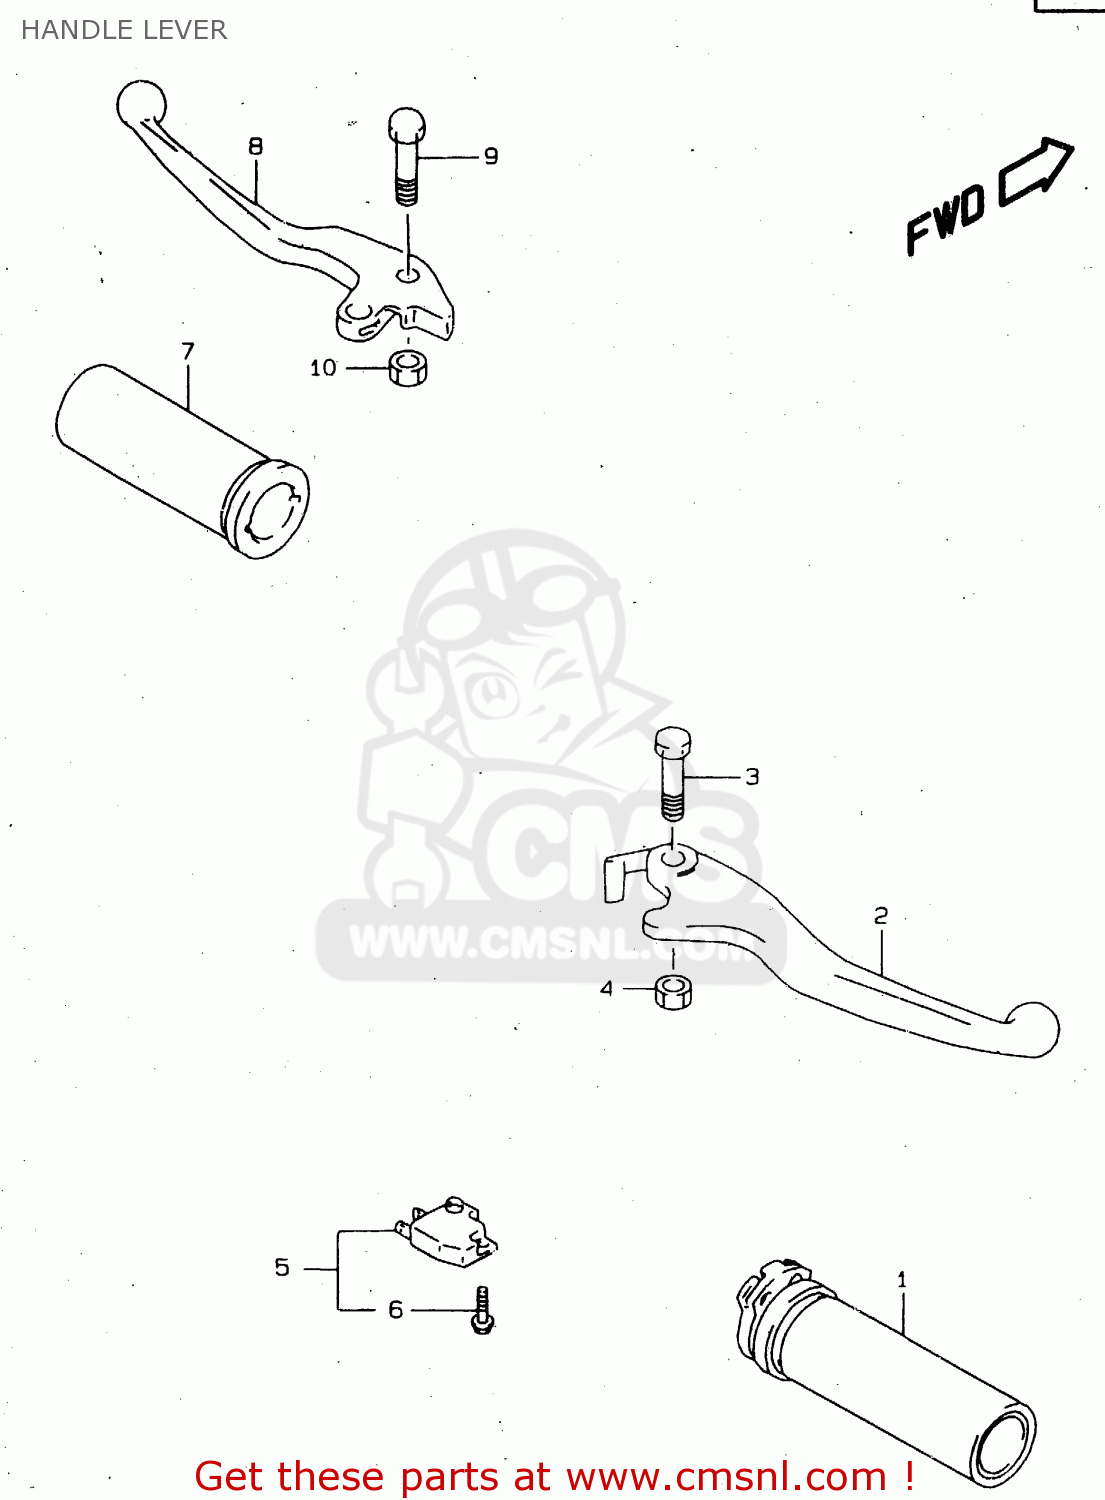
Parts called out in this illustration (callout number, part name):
1	GRIP,THROTTLE
2	LEVER,BRAKE
3	BOLT,LEVER SET
4	NUT 6MM
5	SWITCH ASSEMBLY,STOP
6	SCREW
7	GRIP,L
8	LEVER,CLUTCH (SILVER)
9	BOLT,LEVER SET
10	NUT 6MM
